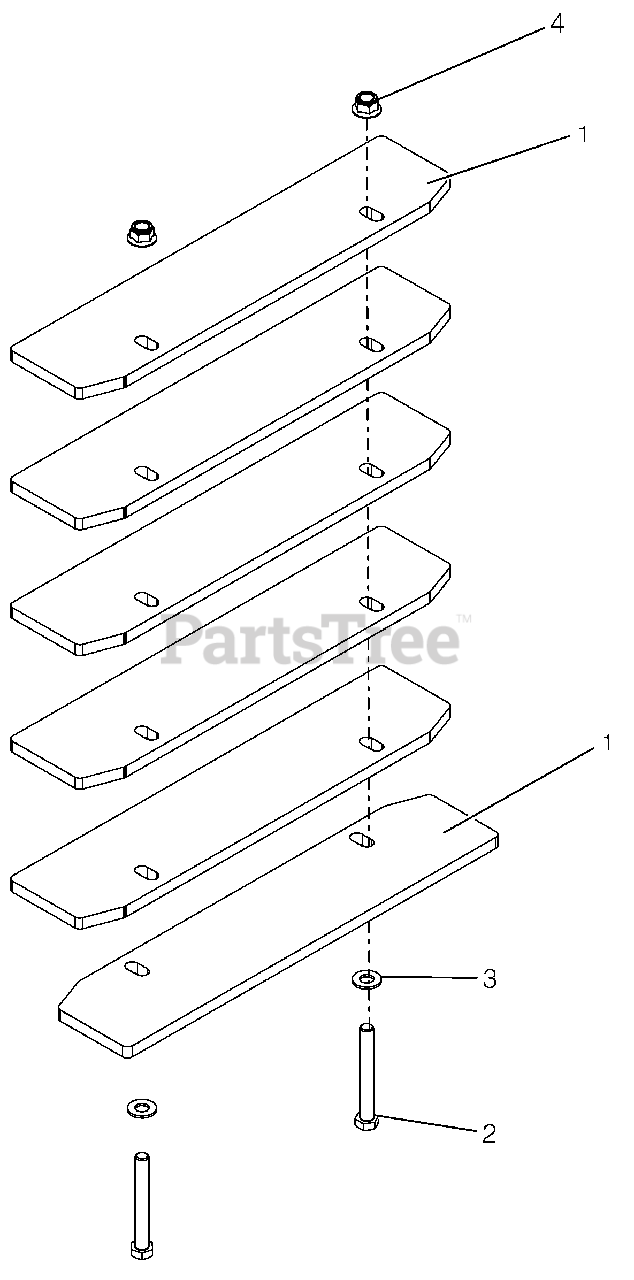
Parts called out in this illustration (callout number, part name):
1	PLATE, COUNTER WEIGHT
2	@BLT-HEX .50-13X4.00 GR5 YWZC
3	@WSHR-FL-STL.531X1.06X.095YWZC
4	@NUT-LK-NYL-FLG .50-13 YWZC
